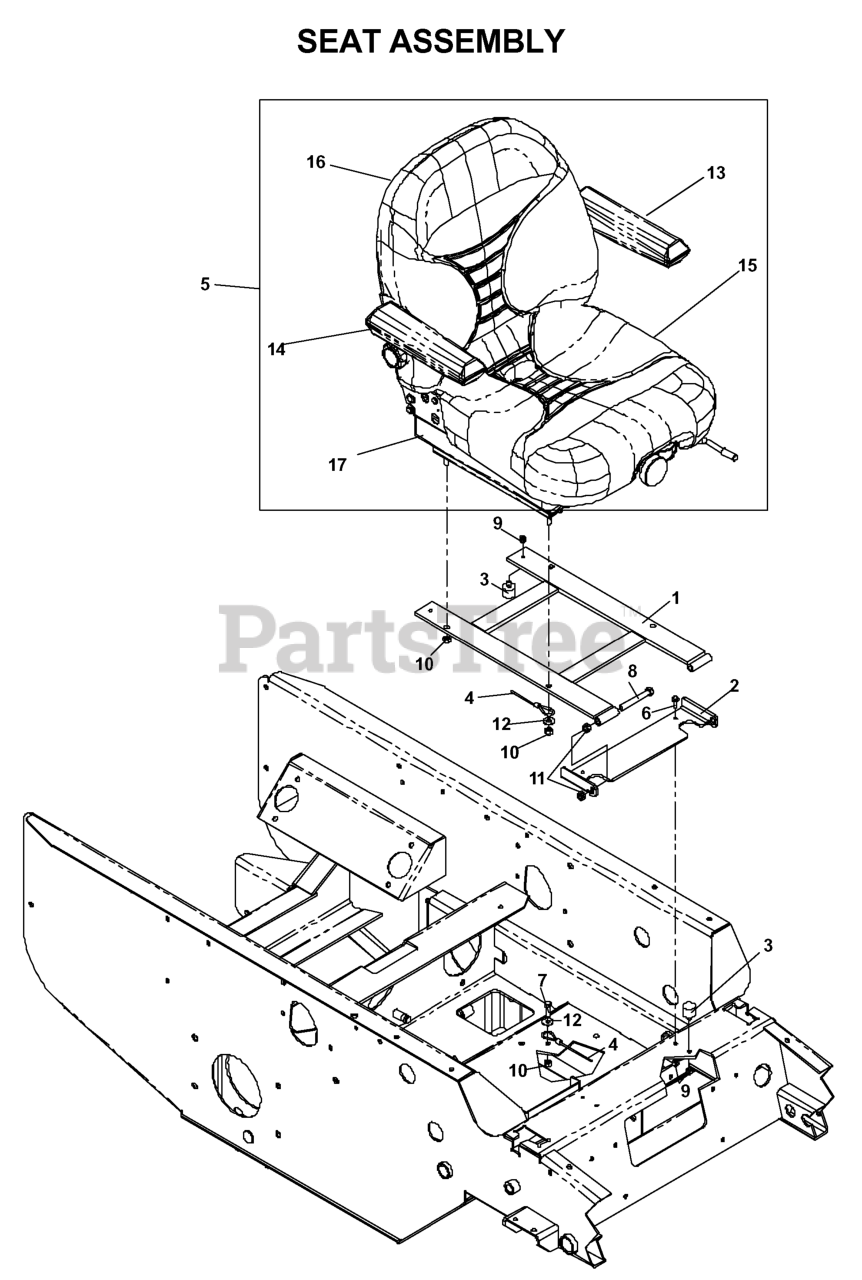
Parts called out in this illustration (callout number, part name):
1	SEAT MOUNT
2	SEAT BKT. W/PAINT
3	STUD/PLATE MOUNT
4	SEAT LANYARD
5	SEAT, SUSPENSION
6	HCS 1/4C X 3/4 HCS
7	HCS 5/16C X 1
8	HCS 3/8C X 3
9	NUT.1/4-20.HEX.NYLOC.ZD
10	NUT 5/16 NYLOC
11	NUT 3/8C CENTERBLOCK
12	WASHER 5/16 FLAT
13	ARMREST KIT, LH
14	ARMREST KIT, RH
15	SEAT CUSHION KIT
16	BACK CUSHION KIT
17	SLIDE KIT, SEAT ADJ
539108745	SWITCH-SNAP MOUNT KIT
